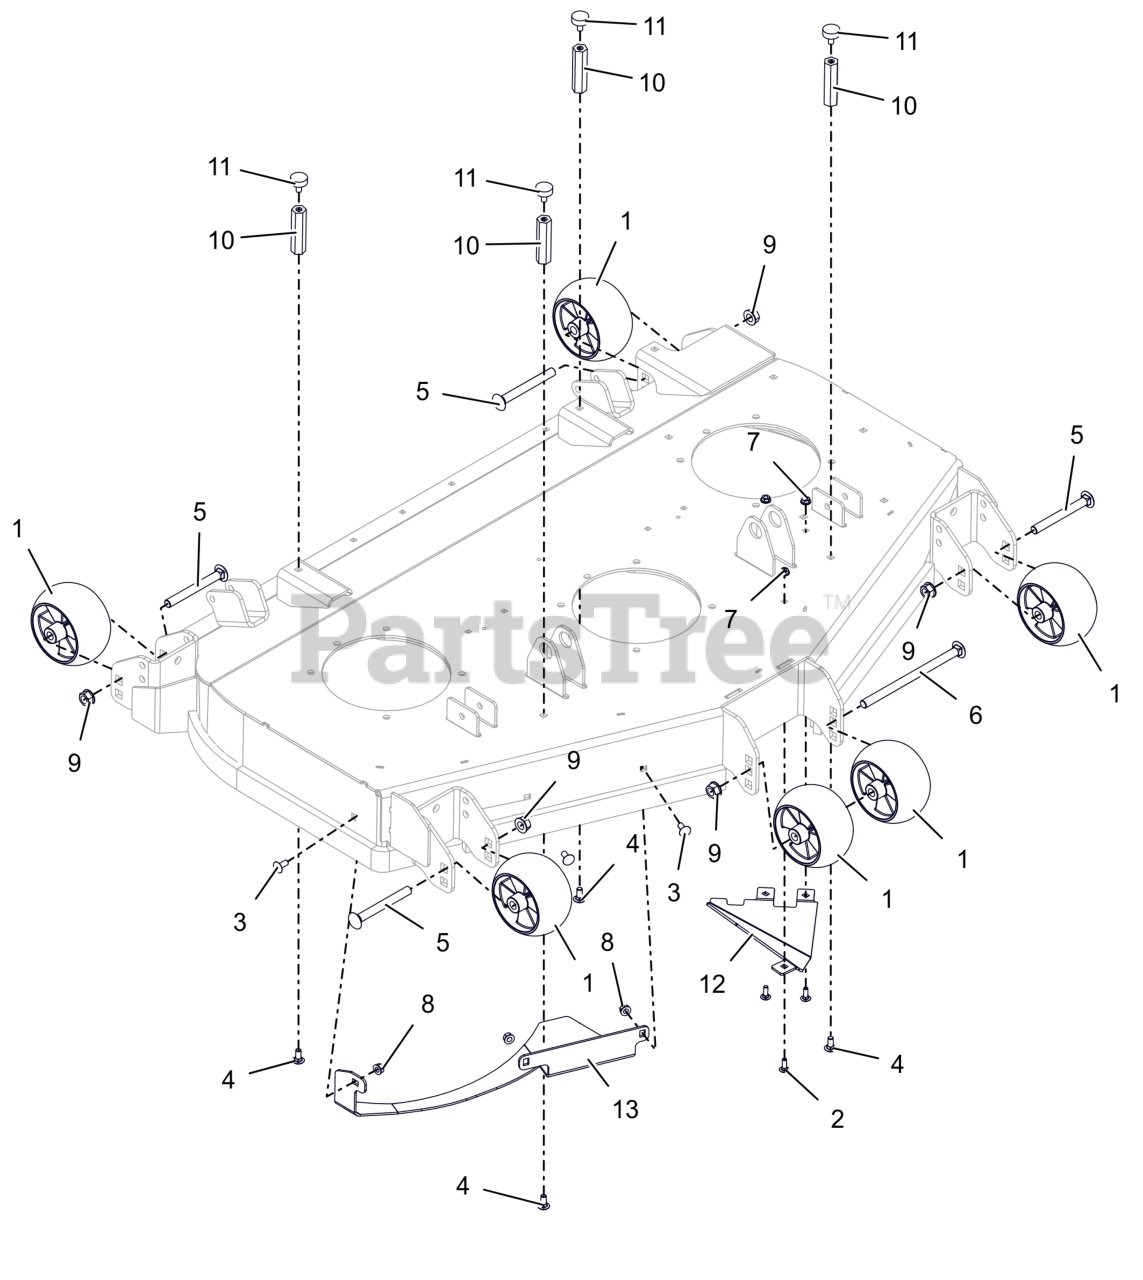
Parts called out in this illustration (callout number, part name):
1	WHEEL, ANTI SCALP - 5X3 CTR W/RIBS
2	BLT, RHSN .25-20X.750 G5 ZCC
3	BLT, RHSSN.31-18X.750 G5 ZCC
4	BLT, RHSN .31-18X.75 G5 ZCC LT
5	BLT-RHNS .50-13X4.50 G5 ZCC NS
6	BLT-RHSN .50-13X8.00 G5 ZCC NS
7	NUT-LK-CTR-FLG .25-20 ZC120
8	NUT,LK-CTR-FLG .31-18 GF ZCC
9	NUT-LK-CTR-FLG .500-13 GG ZCC
10	NUT, COUPLING .31-18 X 3.00
11	BUMPER, RUBBER
12	BAFFLE, 48" TRIANGLULAR INSERT (ORANGE)
13	DEFLECTOR, BAFFLE BOLT-IN (ORANGE)
